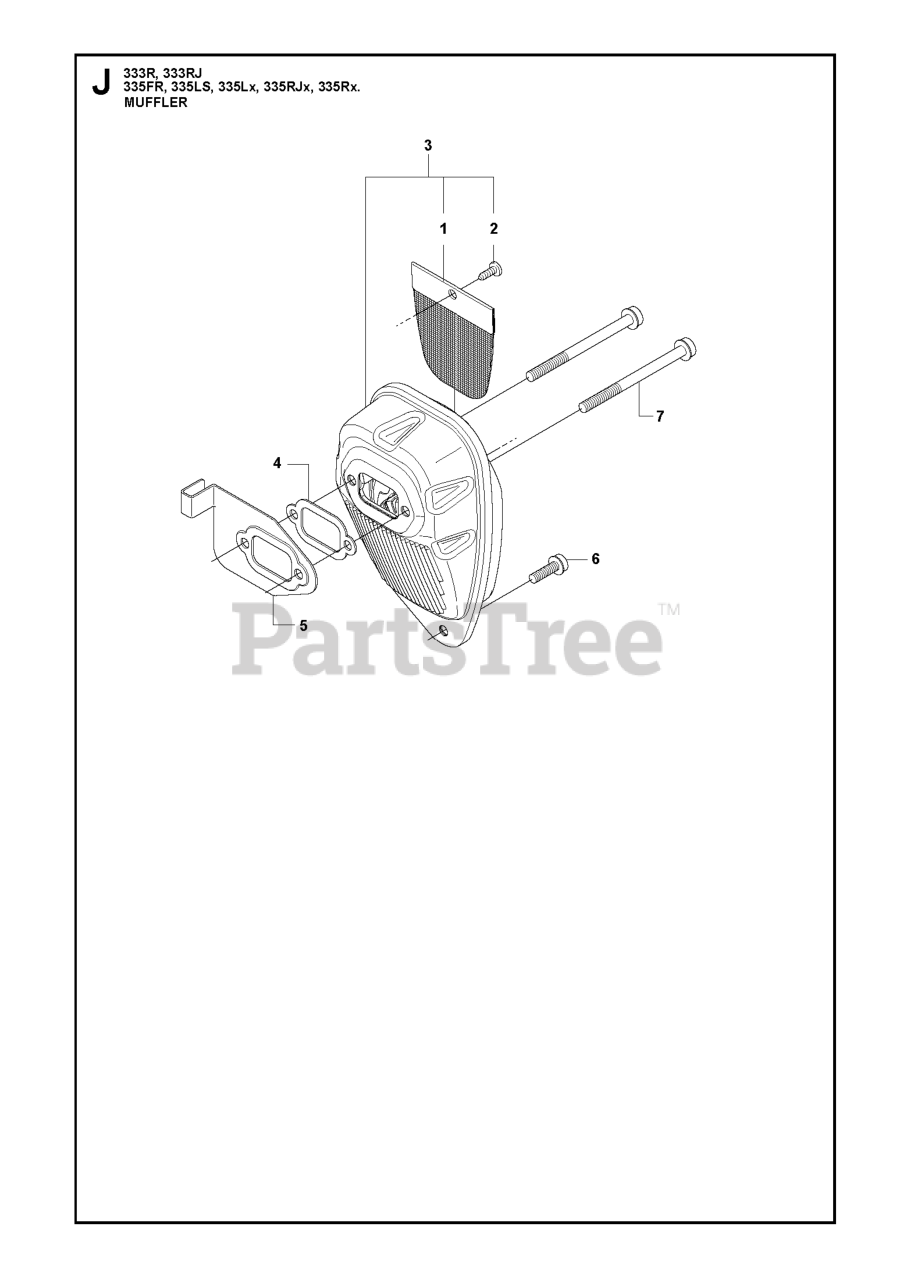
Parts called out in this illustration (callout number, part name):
1	SPARK ARRESTER
3	MUFFLER KIT COMPLETE
3	MUFFLER
4	GASKET MUFFLER
